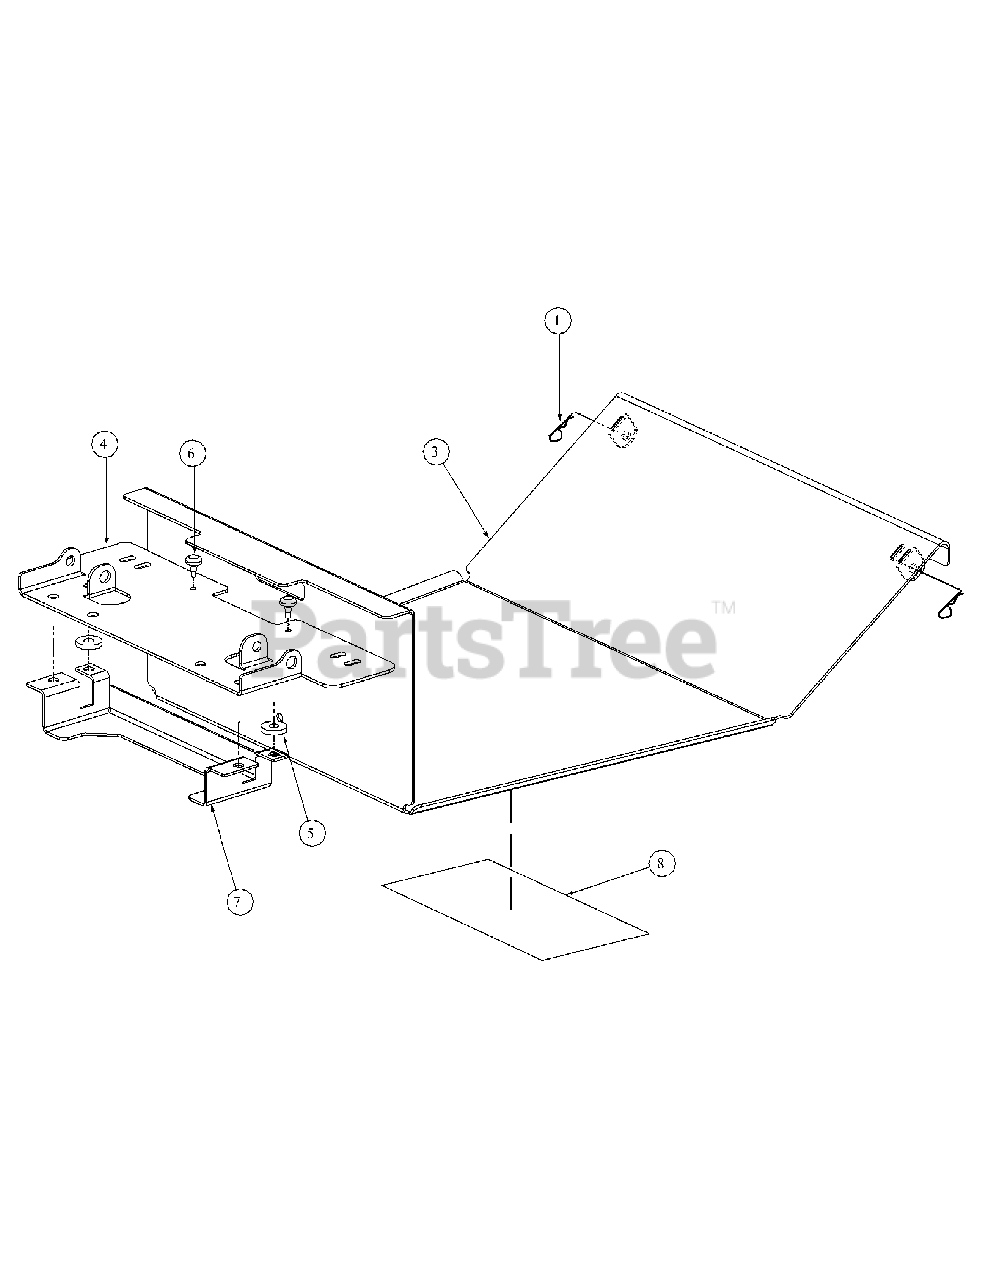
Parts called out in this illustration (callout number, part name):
1	Hair Pin, 3/8-1/2
3	Floor Panel Assembly
5	Washer
6	Rubber Bumper, .62 OD x .22 Thick
7	Support, Seat Bracket
8	Label, Belt Routing and Lubrication
